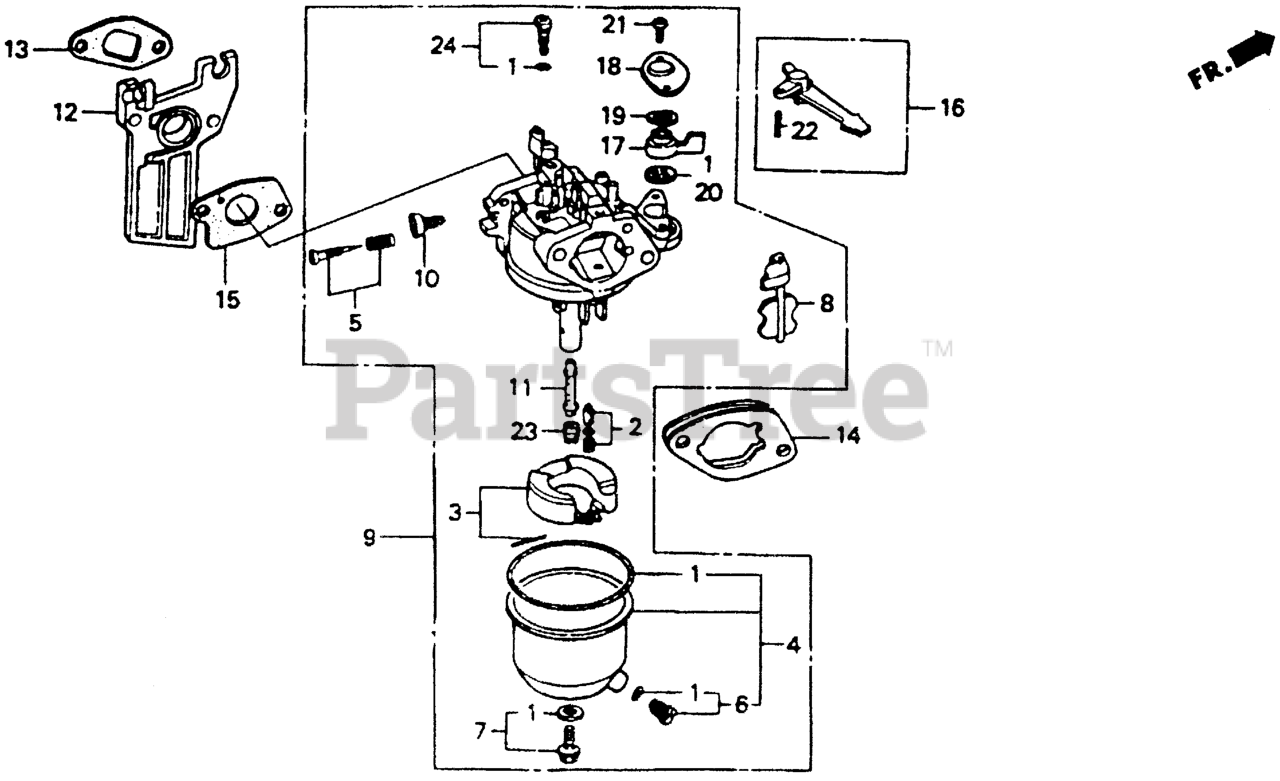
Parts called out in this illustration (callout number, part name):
1	GASKET SET
2	VALVE SET, FLOAT (CARBURETOR NO.) (SEAT NOT INCLUDED)
3	FLOAT SET
4	CHAMBER SET, FLOAT (CARBURETOR NO.)
4	CHAMBER SET, FLOAT (CARBURETOR NO.) (FOR BE12A A)
5	SCREW SET, PILOT (Honda Code 1441500). (CARBURETOR NO.)
6	SCREW SET, DRAIN (Honda Code 1672187). (CARBURETOR NO.)
7	SCREW SET B
7	SCREW SET
8	CHOKE SET
9	CARBURETOR ASSY. (BE05A A)
9	CARBURETOR ASSY. (BE05A B)
9	CARBURETOR ASSY. (BE05A D)
9	CARBURETOR ASSY. (BE05A E)
10	SCREW, THROTTLE STOP
11	NOZZLE, MAIN
12	INSULATOR, CARBURETOR
13	GASKET, INSULATOR
14	SPACER, CARBURETOR
15	GASKET, CARBURETOR
16	LEVER, CHOKE (STD)
17	LEVER, VALVE
18	PLATE, LEVER SETTING (CARBURETOR NO.)
19	SPRING, PETCOCK LEVER (CARBURETOR NO.)
20	GASKET, VALVE
21	SCREW, PAN (3X8)
21	SCREW, PAN (3X8) (CARBURETOR NO.)
22	PIN, SPRING (2X12)
23	JET, MAIN (#62) (Honda Code 0635482). (CARBURETOR NO.)
23	JET, MAIN (#65) Use up to Engine SN BB30A D.
23	JET, MAIN (#68) Use up to Engine SN BB30A D.
24	JET SET, PILOT (#35)
